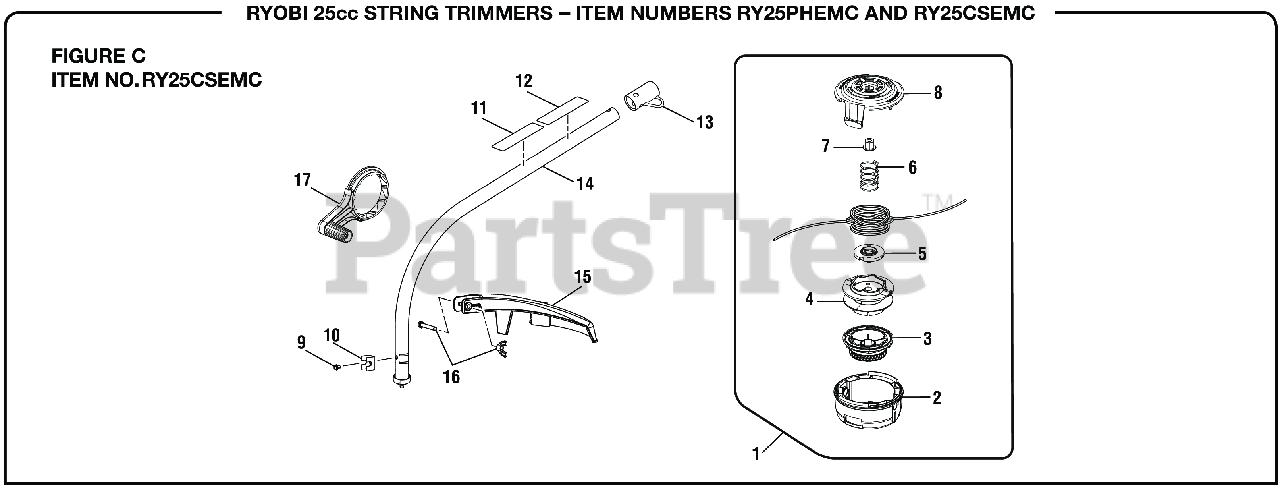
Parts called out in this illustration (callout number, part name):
1	Trimmer Head Assembly (.095)
2	Lower Housing
3	Bump Knob (Green)
4	Spool Assembly
5	String Guide
6	Compression Spring
7	Flange Nut (M8)
8	Upper Housing
9	Screw (#10-32 x 3/8 in., Hex Washer Hd. S.T.)
11	Ryobi EXPAND-IT Label
12	Warning Icon Label
13	Storage Hanger Cap
14	Curved Shaft Assembly
15	Grass Deflector Assembly
16	Fastener Parts Kit
17	Crank Handle Assembly
